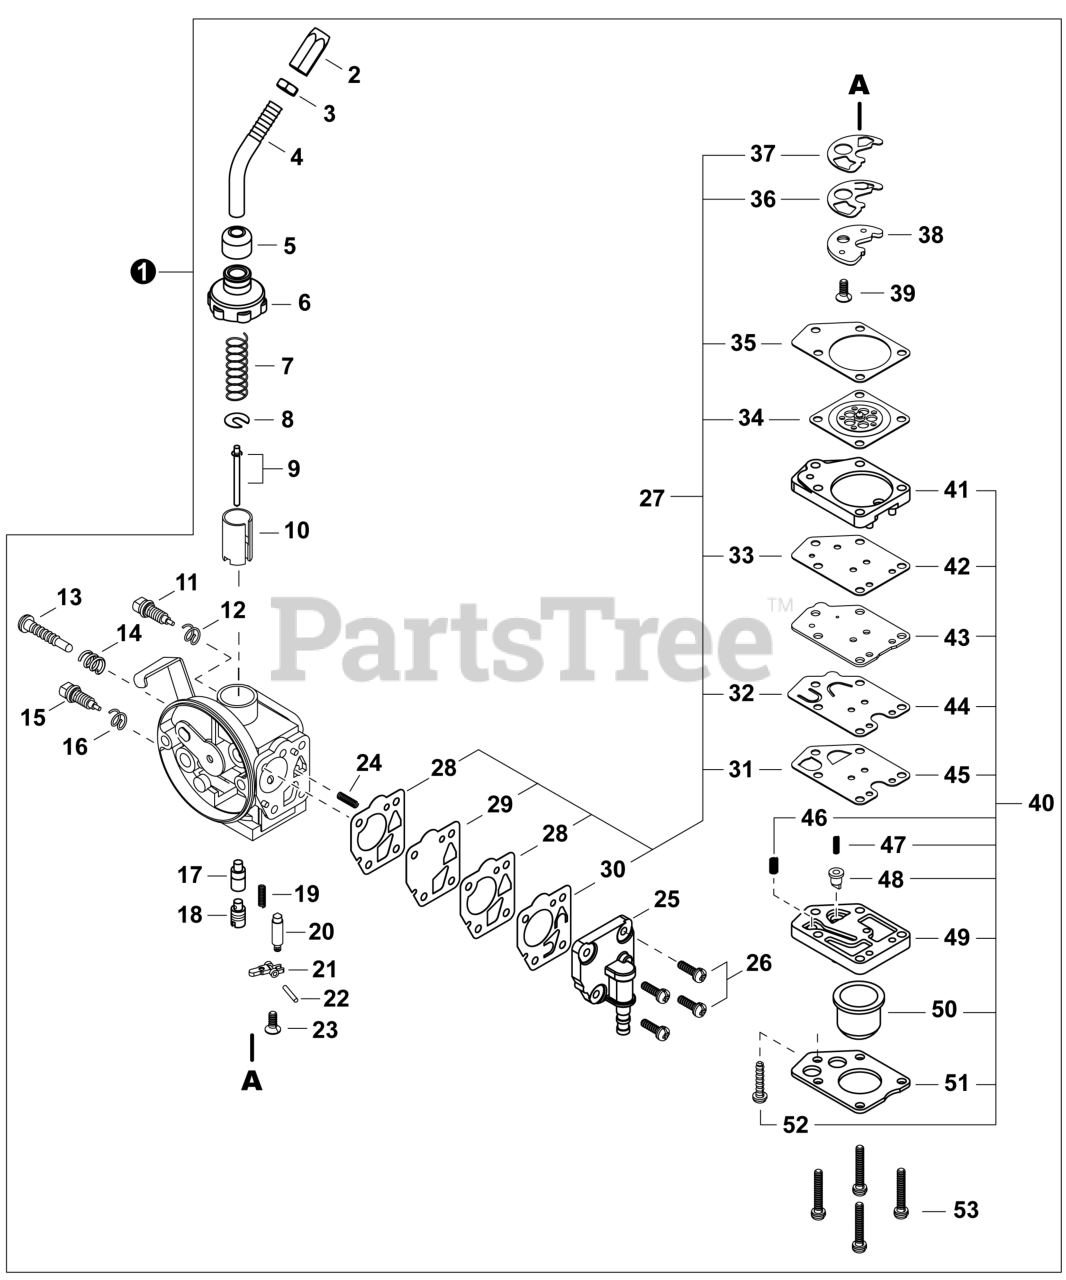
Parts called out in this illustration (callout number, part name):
1	CARBURETOR DPV11W-19A
2	ADJUSTER, CABLE
3	NUT, LOCK
4	PIPE, CABLE ADJUSTER
5	CAP, DUST
6	CAP, CARBURETOR
7	SPRING, THROTTLE
8	WASHER, SPRING SUPPORT
9	NEEDLE, JET
10	VALVE, SLIDE
11	SCREW, SLOW AIR
13	SCREW, IDLE ADJUST
15	SCREW, MAIN ADJUST
17	JET, MAIN
18	HOLDER, MAIN JET
20	VALVE, INLET NEEDLE
21	LEVER, METERING
22	PIN, METERING LEVER
23	SCREW M3x8
25	PUMP BODY
27	GASKET / DIAPHRAGM KIT
28	GASKET, DIAPHRAGM
29	DIAPHRAGM, METERING
30	VALVE, PUMP
32	VALVE, CHECK
34	DIAPHRAGM, METERING
35	GASKET, METERING DIAPHRAGM
36	VALVE, CHECK
37	PACKING
39	SCREW M3x8
40	PURGE PUMP KIT
41	COVER, PUMP
43	PLATE, PUMP
44	VALVE, CHECK
48	VALVE, CHECK
49	BODY, PURGE
50	BULB, PURGE
51	RETAINER, PURGE BULB
53	SCREW 3x20
